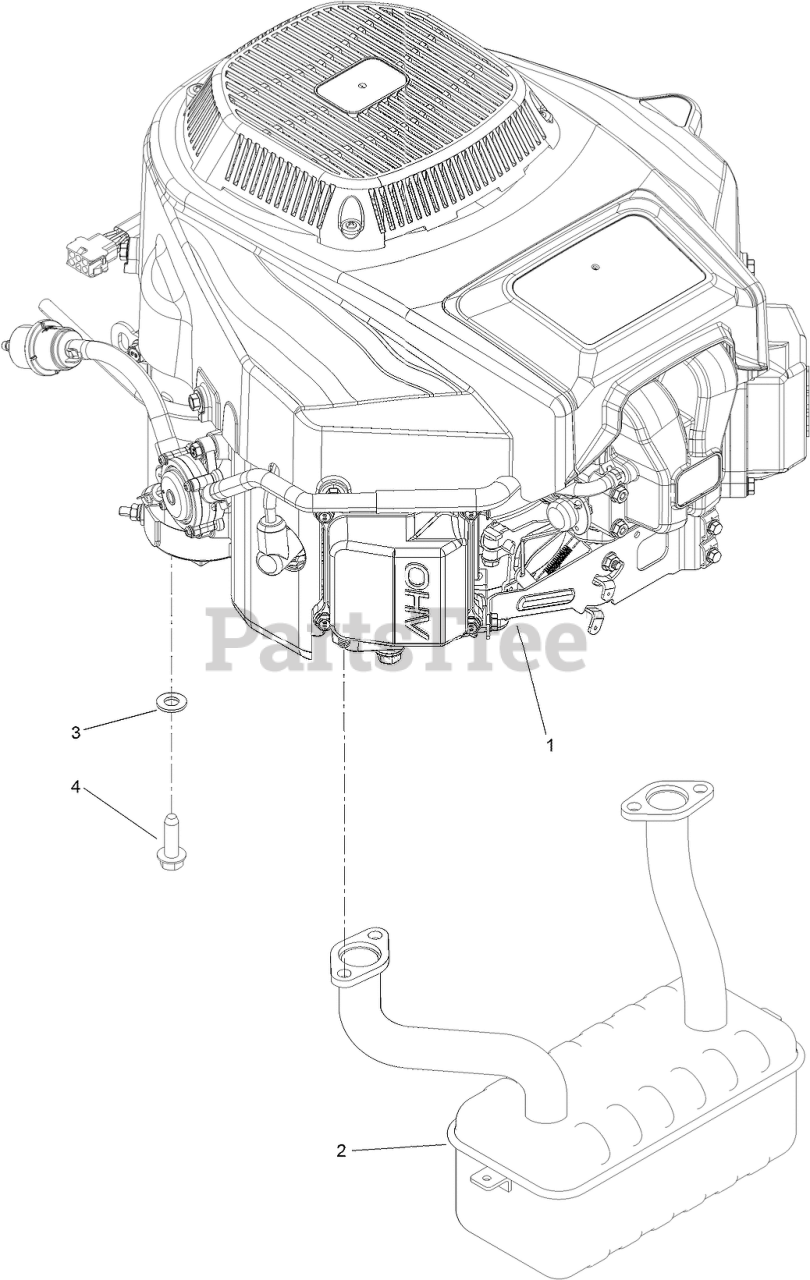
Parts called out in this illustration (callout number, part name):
1	ENGINE-2P77F
2	MUFFLER
3	WASHER-FLAT
4	SCREW-THD
